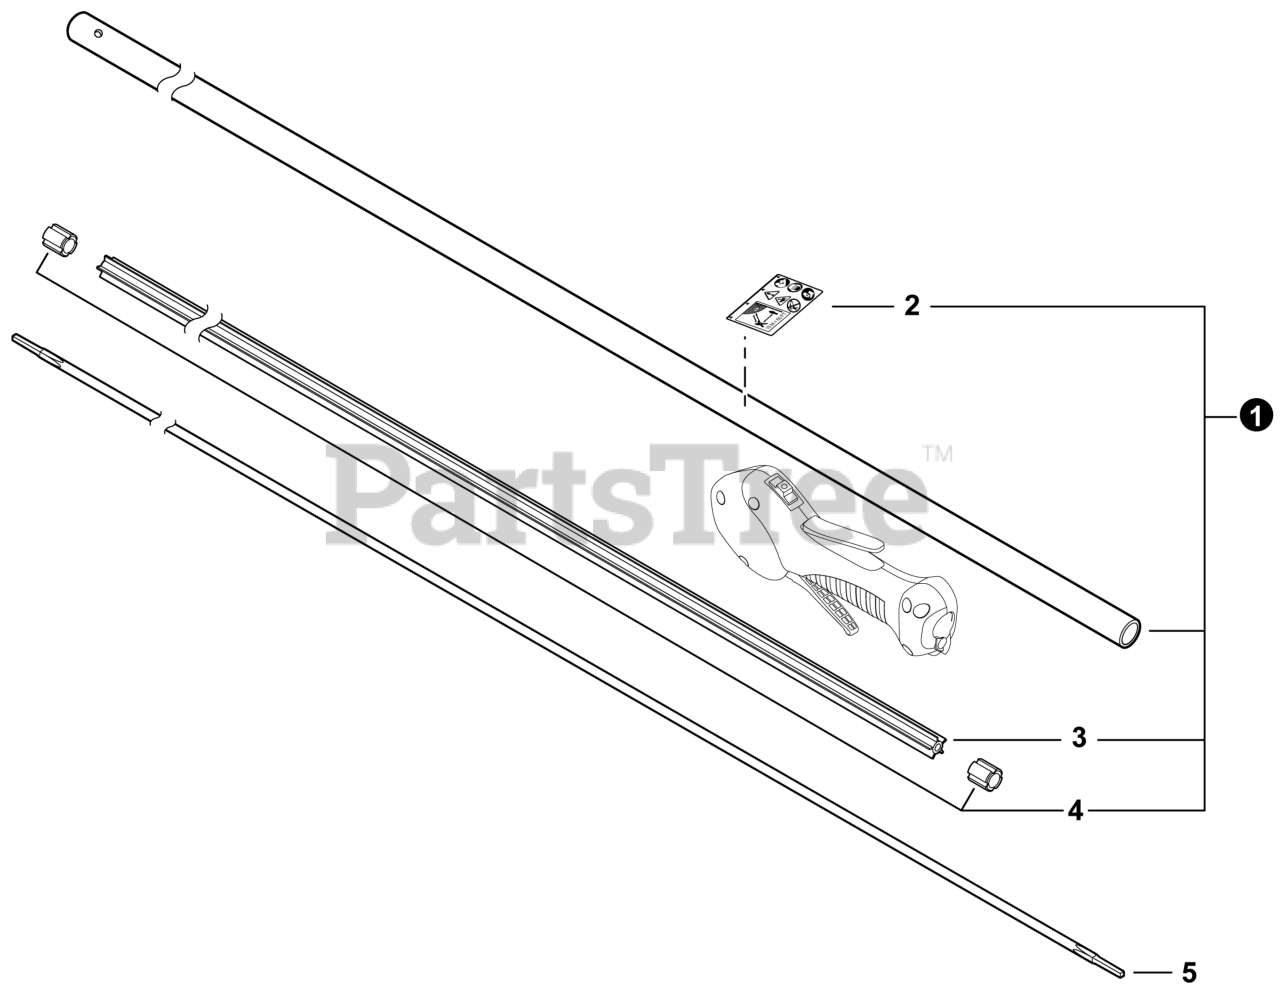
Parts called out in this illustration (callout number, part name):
1	MAIN PIPE ASSY
2	LABEL - CAUTION ISO
3	LINER - FLEXIBLE
5	DRIVESHAFT - FLEXIBLE
